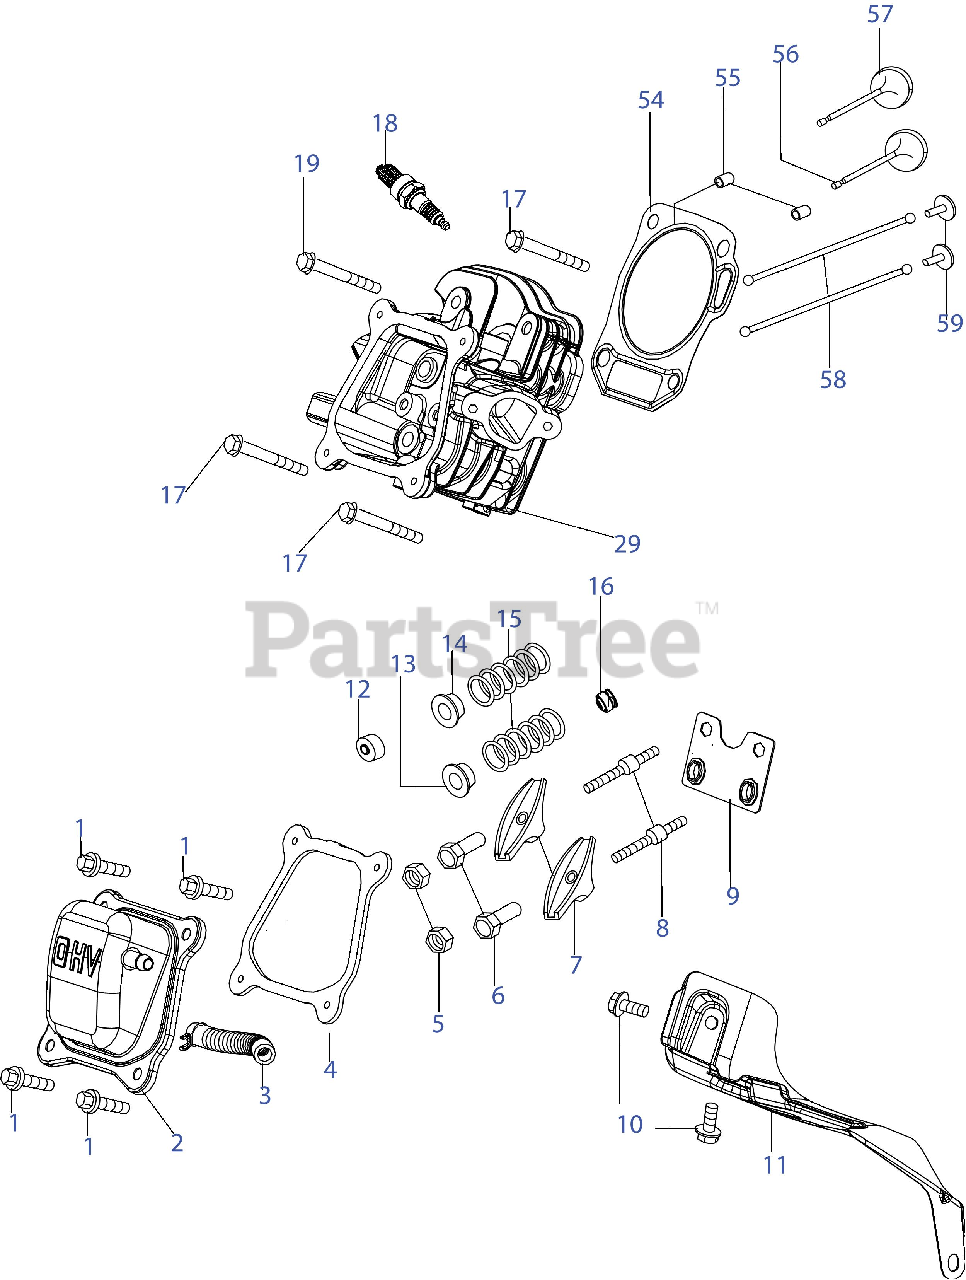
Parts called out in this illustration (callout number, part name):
1	Bolt M6x16
2	Cylinder Head Cover
3	Venting House
4	Gasket, Valve Cover
7	Rocker Arm
8	Rocker Arm Stud
9	Rocker Arm Base
10	Bolt M6x12
12	Rotator,Exhaust Valve
13	Intake Valve Spring Seat
14	Exhaust Valve Spring Seat
15	Spring Valve
16	Oil Seal,Valve
17	Flange Bolt M8x60
18	Spark Plug(F6Rtc)
19	Flange Bolt M8x70
29	Cylinder Head
54	Gasket,Cylinder Head
55	Dowel Pin 10x16
56	Valve Intake
57	Valve Exhaust
